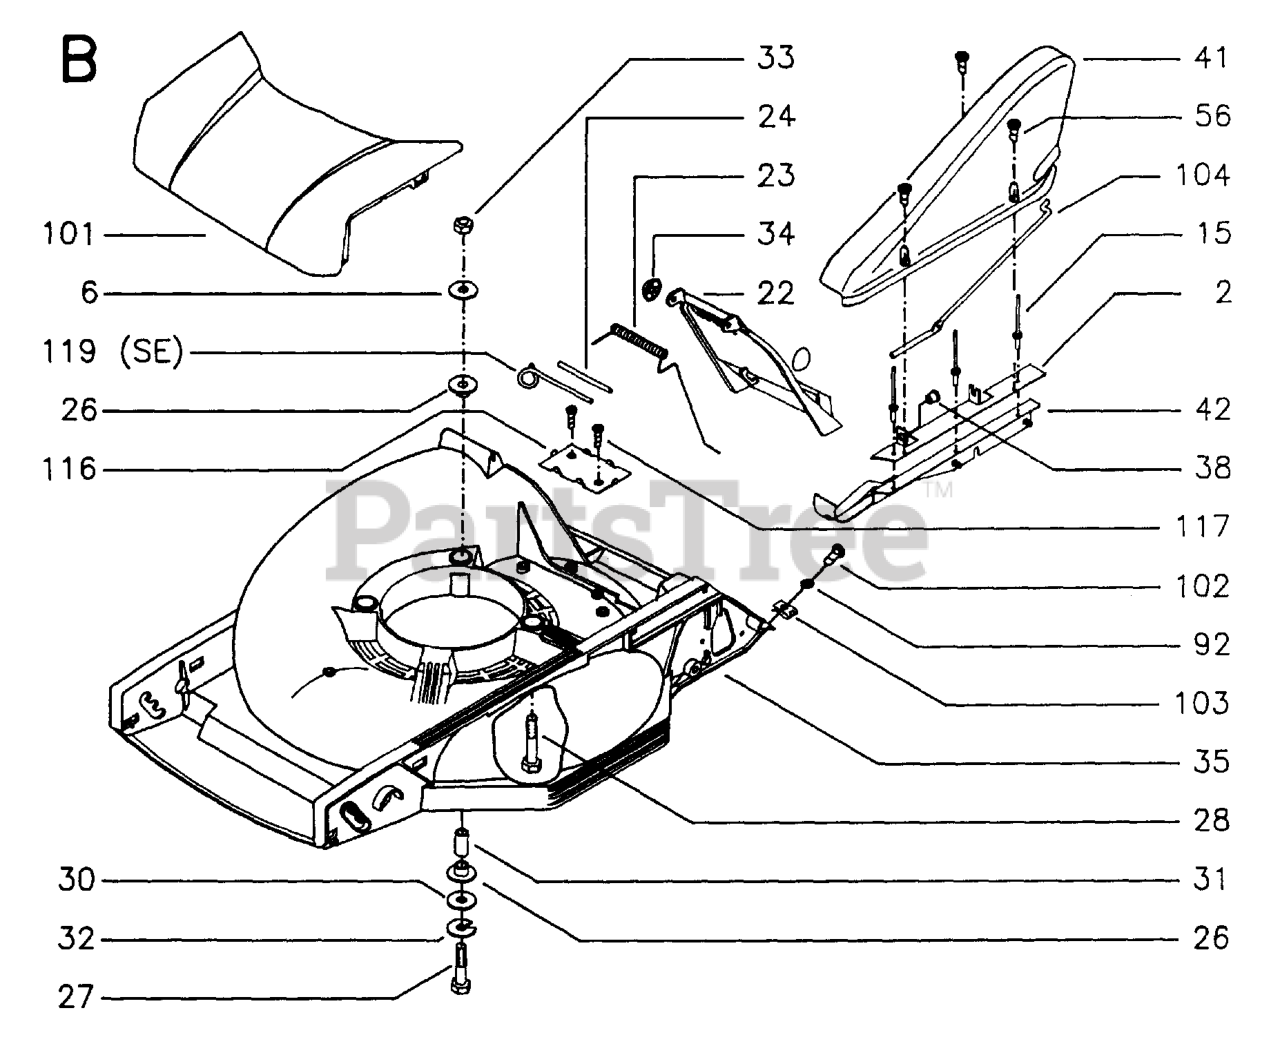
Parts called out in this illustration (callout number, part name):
24	PIN
32	SPRING WASHER
33	LOCKNUT M8
103	LOCK PLATE
119	HOLDER
